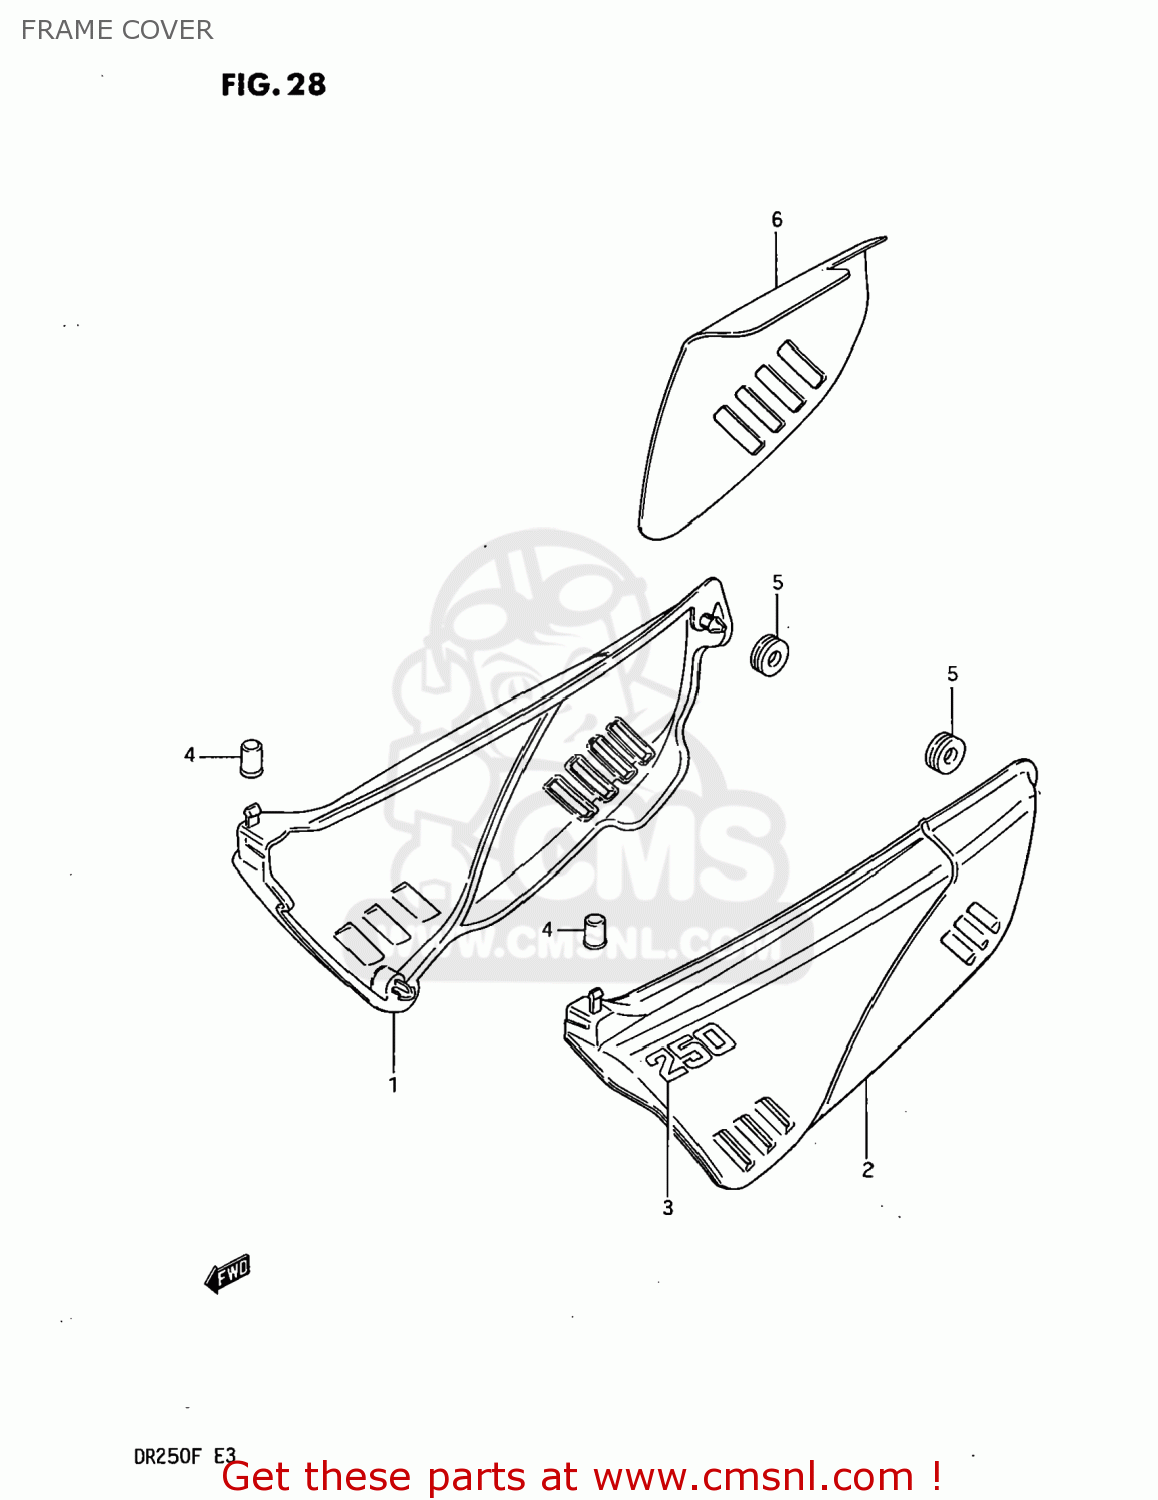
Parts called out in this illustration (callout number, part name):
1	COVER,FRAME,RIGHT
2	COVER,FRAME,LEFT
3	EMBLEM
4	CUSHION
5	CUSHION
6	HEAT SHIELD,FRAME COVER
